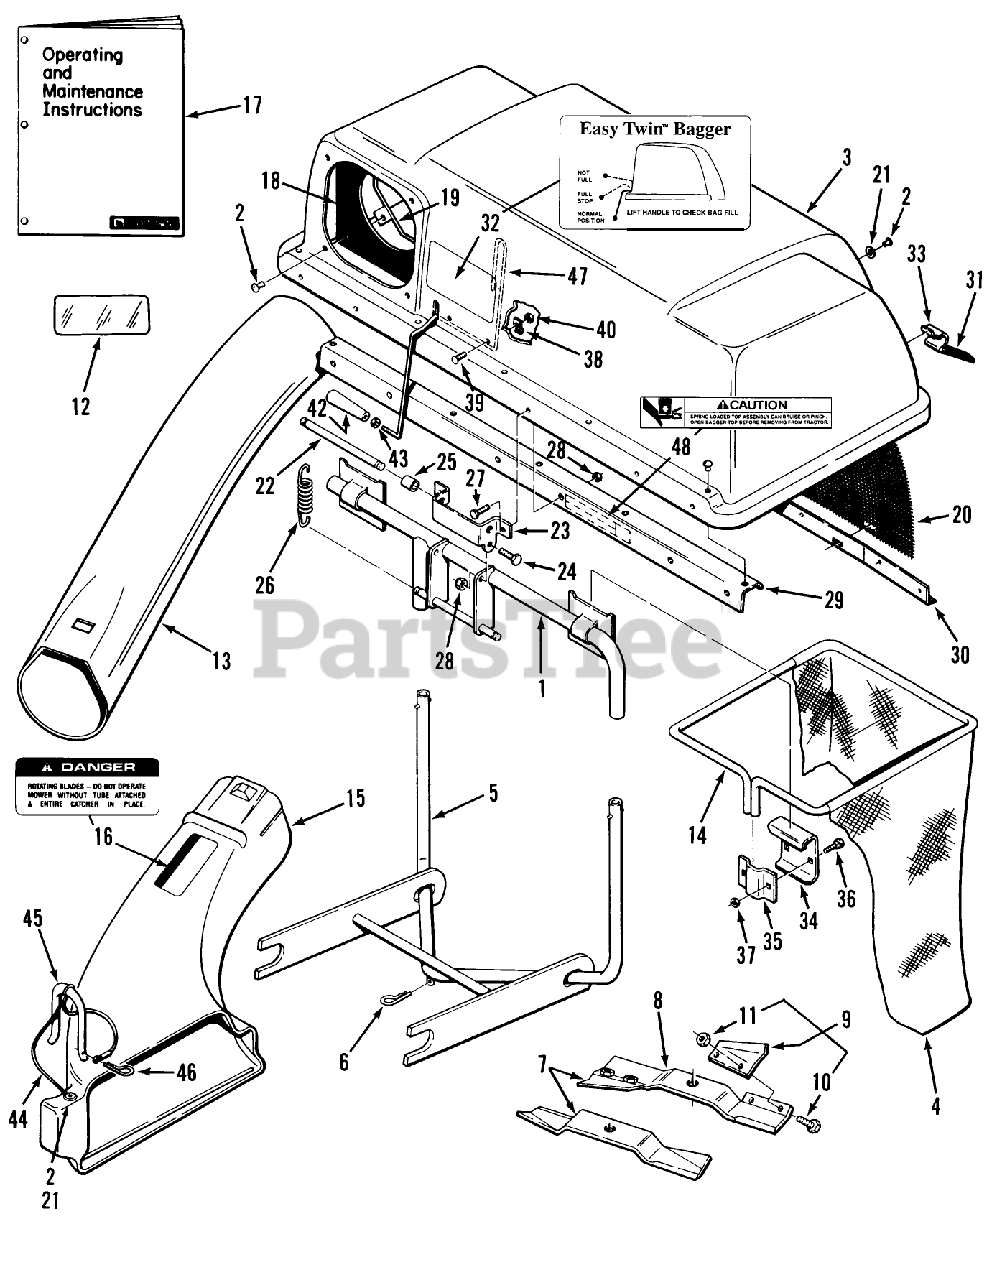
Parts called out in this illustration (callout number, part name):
2	RIVET-BLIND
5	ASS'Y-QUICK ATTAC *B
6	Hairpin
7	KIT-BLADE (SERVICE)
8	ASS'Y-HI LIFT BLADE
9	S/A 37 LIFT TAB KIT
10	BOLT 5/16-18X5/8
11	NUT-HEX
12	DECAL-OVERLAY
13	CHUTE-BAGGER (L)
16	DECAL-DANGER
17	Operating and Maintenance Instructions
19	CLAMP-SEAL
20	SCREEN-BAGGER
22	PIN-SPRING
26	SPRING-EXTENSION
42	HANDLE-TAPERED
44	LANYARD-ELBOW LATCH
45	LATCH-ELBOW
46	Hairpin Cotter
47	FEELER-FILL, BAG
